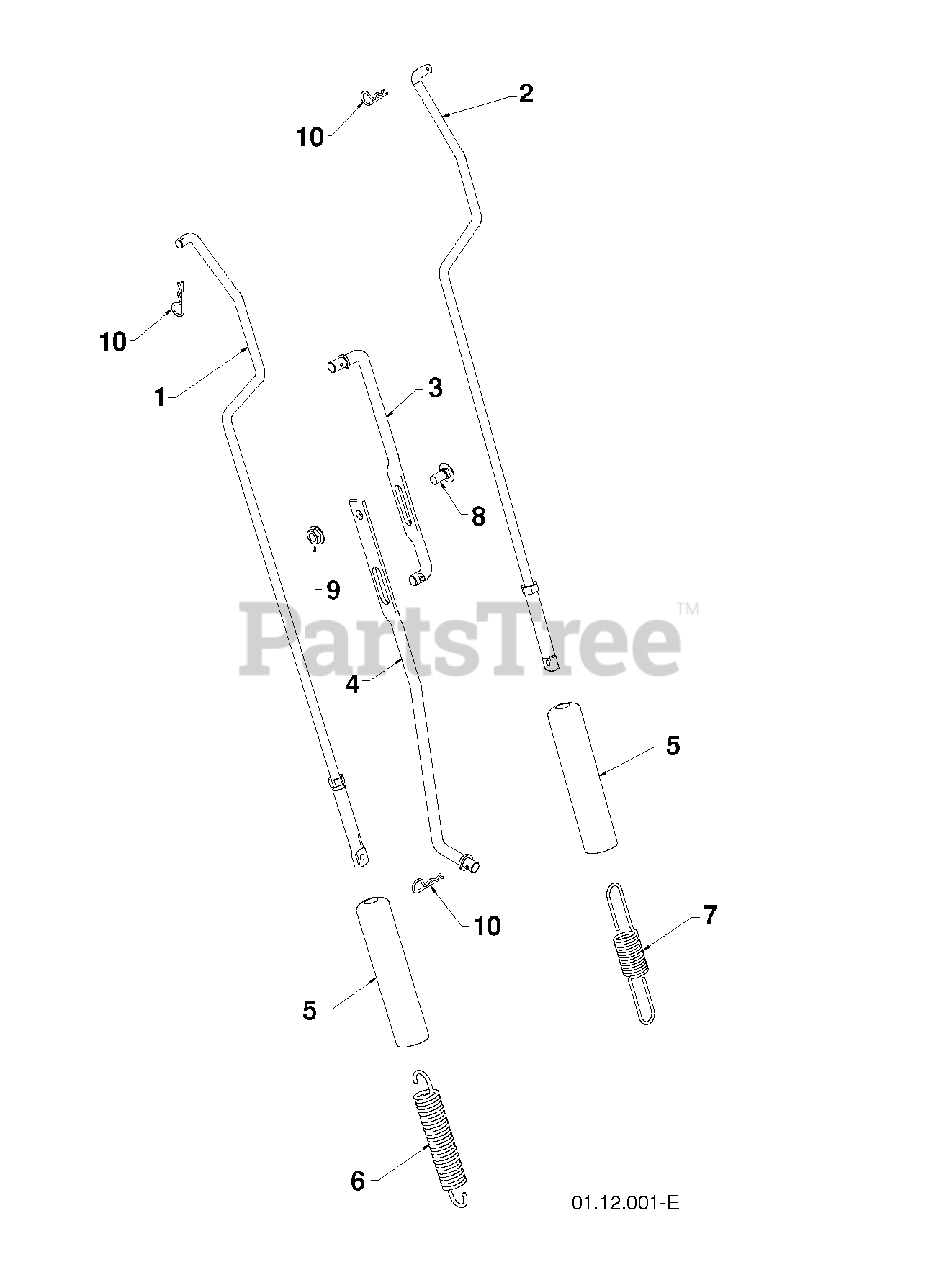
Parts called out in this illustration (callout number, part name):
1	ROD.ASM.IMPELLER
2	ROD.ASM.TRACTION
3	ROD, UPPER SPEED CONTROL
4	ROD, LOWER SPEED CONTROL
5	SLEEVE, SPRING
6	SPRING, AUGER CONTROL
7	SPRING, TRACTION DRIVE
8	BOLT
9	NUT.FLANGE.5/16
10	SPRING RETAINER
